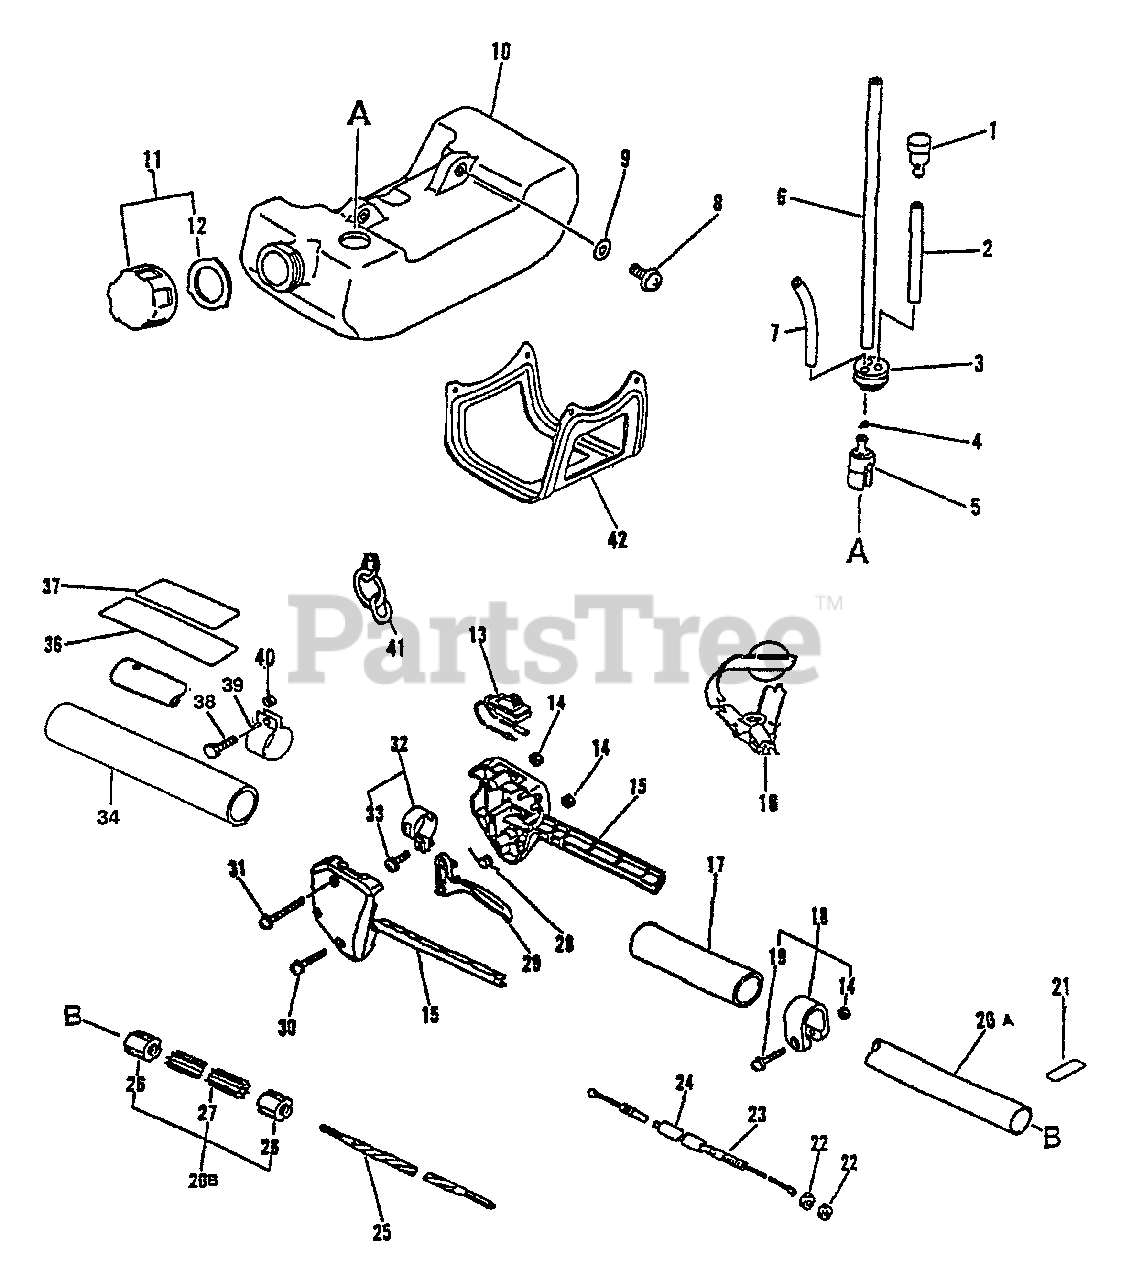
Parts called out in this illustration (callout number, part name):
1	VENT ASSY
2	PIPE, FUEL 3x-5x-70 BLACK
3	GROMMET, FUEL
4	CLIP 6 MM
5	FILTER, FUEL
6	PIPE, FUEL 3x-5x-180
7	PIPE, FUEL RETURN 3×6×90 MM CLEAR
8	SCREW 5×16
9	WASHER 5.5×12×0.8
10	TANK, FUEL
11	CAP ASSY
12	GASKET, FUEL CAP
13	IGNITION SWITCH ASSY
14	NUT M5
15	HANDLE KIT, CONTROL
16	SHOULDER STRAP ASSY
17	GRIP, HANDLE
18	CLAMP KIT
19	SCREW 5×28
20	MAIN PIPE ASSY
21	LABEL - ALIGNMENT
23	CABLE, THROTTLE
25	DRIVESHAFT - FLEXIBLE
27	LINER, FLEXIBLE 21.6×1420
28	SPRING, TORSION
29	TRIGGER, THROTTLE
30	SCREW 5×25
31	SCREW 5×35
32	CLAMP KIT
33	SCREW 5×14
34	GRIP, HANDLE
36	LABEL - CAUTION
37	LABEL - CAUTION
38	BOLT 5×18
40	SPACER, GUARD
41	HOOK
42	GUARD, FUEL TANK
